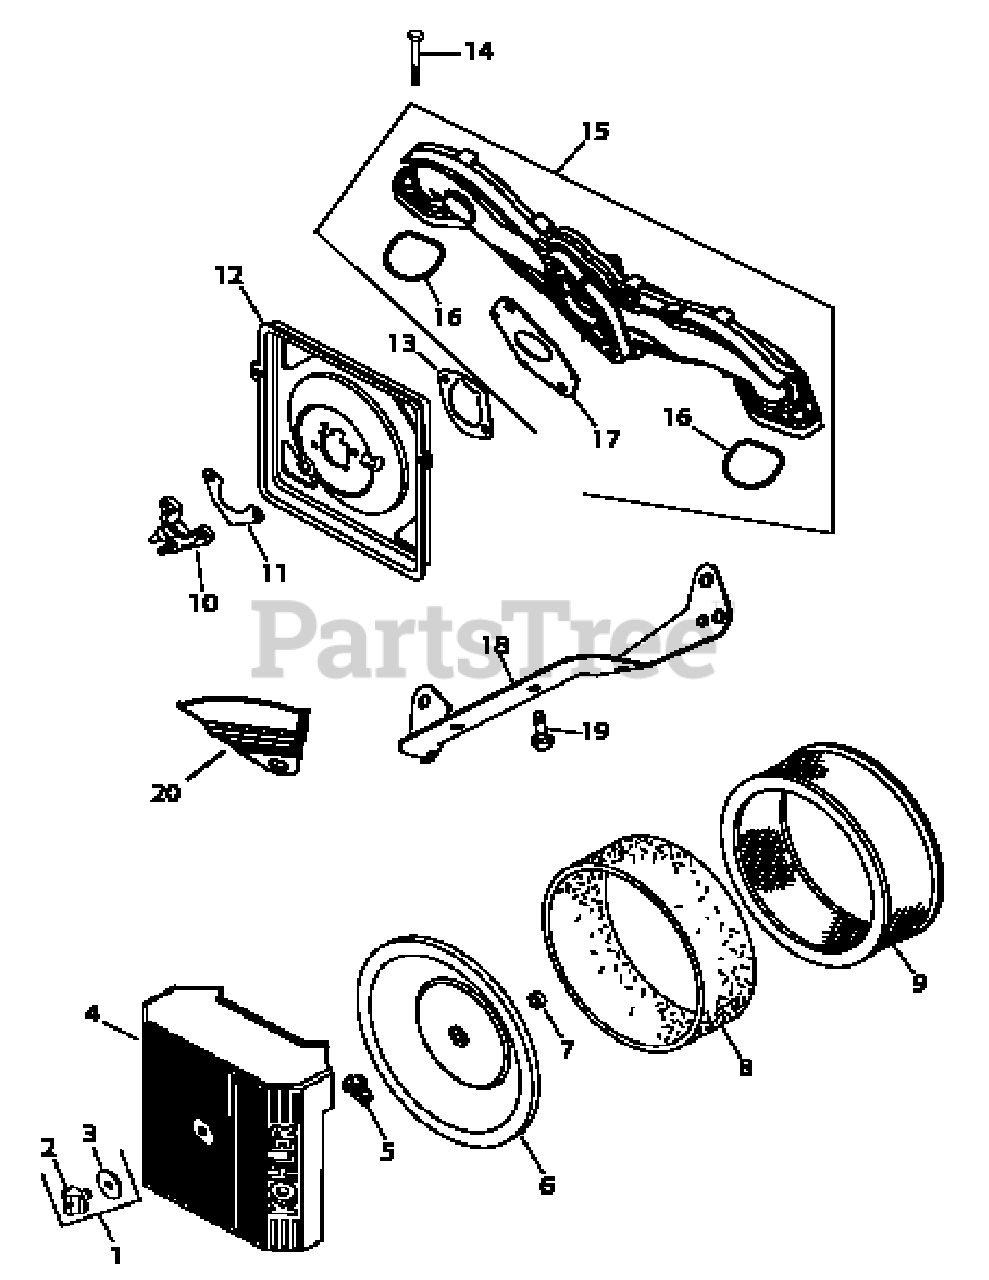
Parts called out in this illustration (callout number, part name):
1	Knob With Seal Kit
4	Air Cleaner Cover
6	Inner Air Cleaner Cover
7	Inner Air Cleaner Seal
8	Precleaner Element
9	Air Cleaner & Precleaner Elements
10	Spit Back Cup
11	Spit Back Cup Gasket
12	Air Cleaner Base
13	Air Cleaner Gasket
14	Hex Flange Screw (M6 x 1.0 x 40)
15	Intake Manifold
16	Intake Port O-Ring
17	Carburetor Gasket
18	Air Cleaner Bracket
19	Hex Flange Screw (M5 x .8 x 10)
20	Spit-back Cup Baffle
